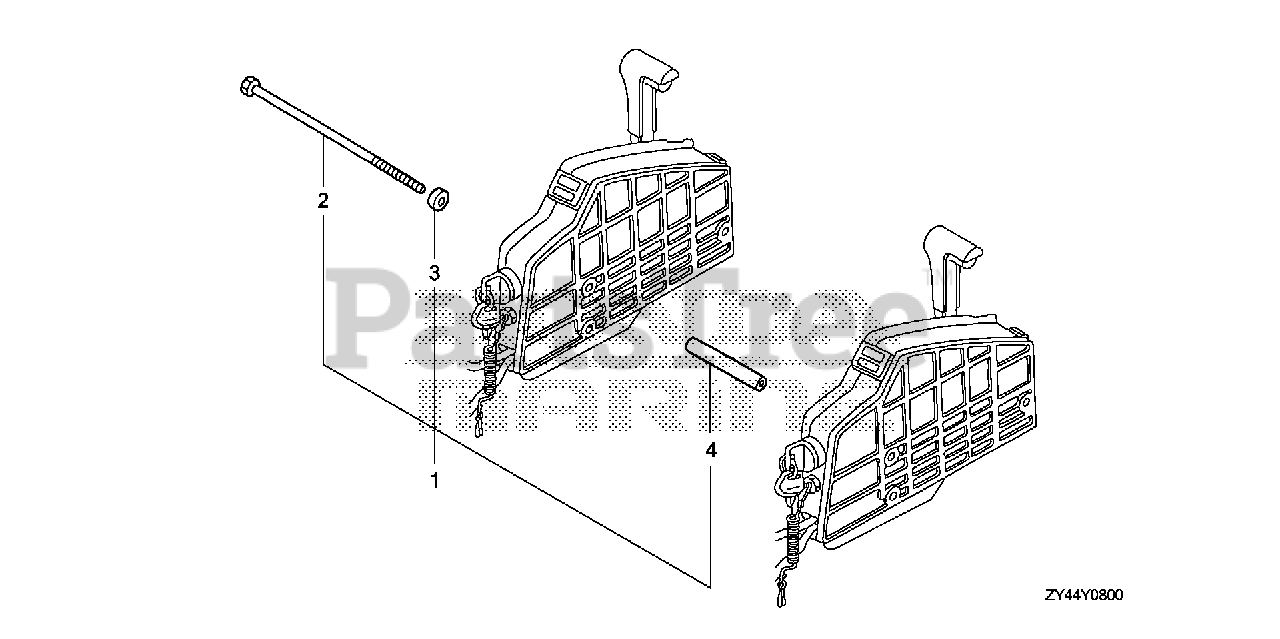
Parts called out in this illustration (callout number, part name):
1	BOLT KIT, SIDE REMOTE CONTROL
2	BOLT, SPECIAL (6X220)
3	COLLAR, DISTANCE (A)
4	COLLAR, DISTANCE (B)
